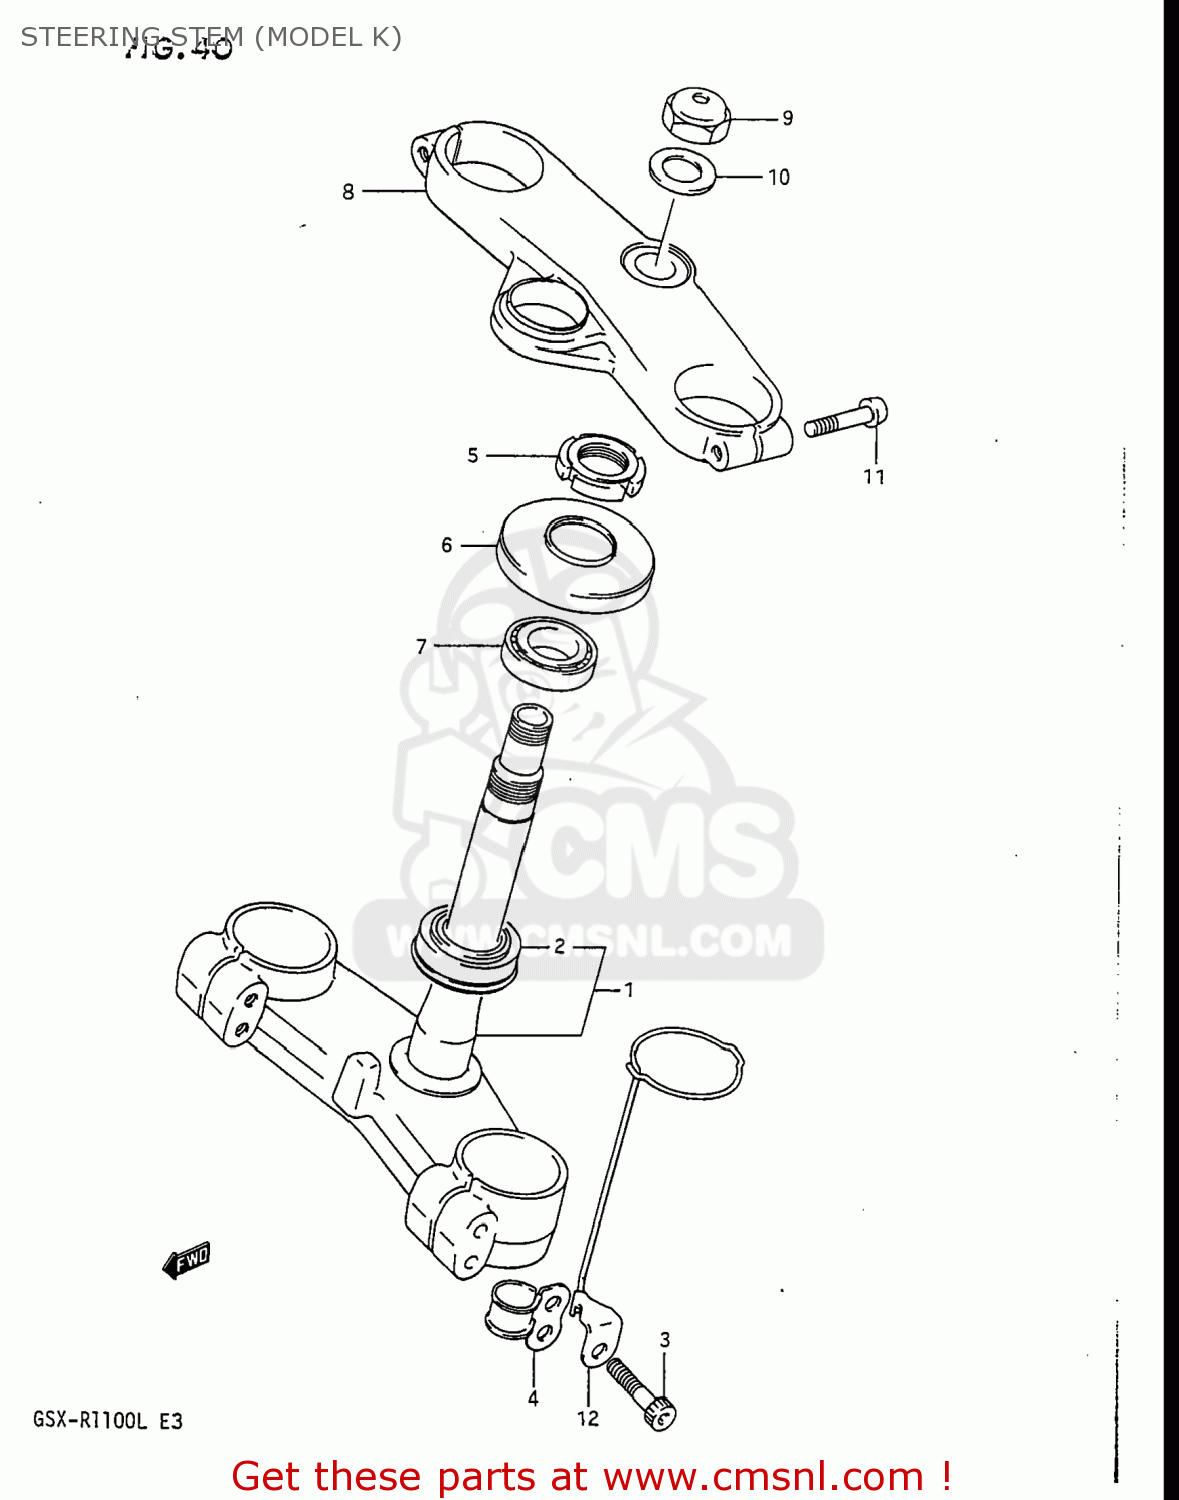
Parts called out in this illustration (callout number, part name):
1	STEM,STEERING
2	BEARING(30X55X17)
3	BOLT 10X45
4	GUIDE,SPEEDOMETER CABLE
5	NUT,STEERING STEM(25X44X10)
6	SEAL OIL
7	TAPER,ROLLER BEARING
8	HEAD,STEERING STEM
9	NUT
10	WASHER(22.5X32X1.6)
11	BOLT,FORK INNER TUBE F
12	HOLDER,STEERING DAMPER
